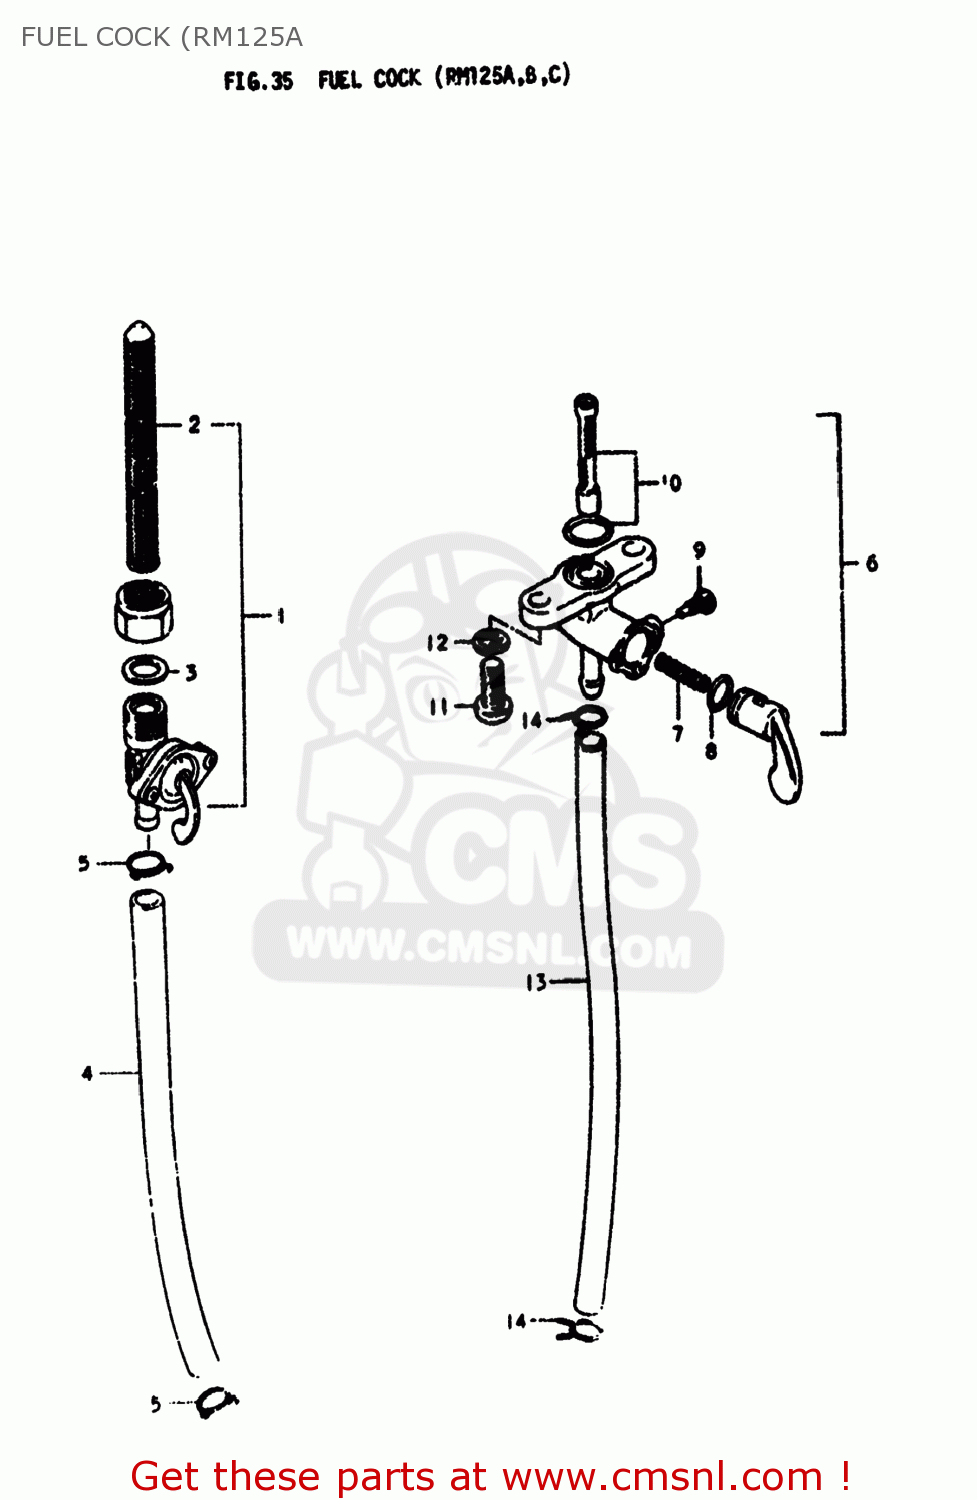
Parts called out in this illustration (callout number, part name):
1	COCK ASSY,FUEL
2	FILTER,FUEL
3	GASKET,FUEL COCK (NAS)
4	HOSE
5	CLIP
6	COCK ASSEMBLY,FUEL
7	SPRING,FUEL COCK VALUE
8	O RING,LEVER
9	SCREW
10	FILTER SET FUEL
11	SCREW
12	LOCK WASHER
13	HOSE
14	CLIP
